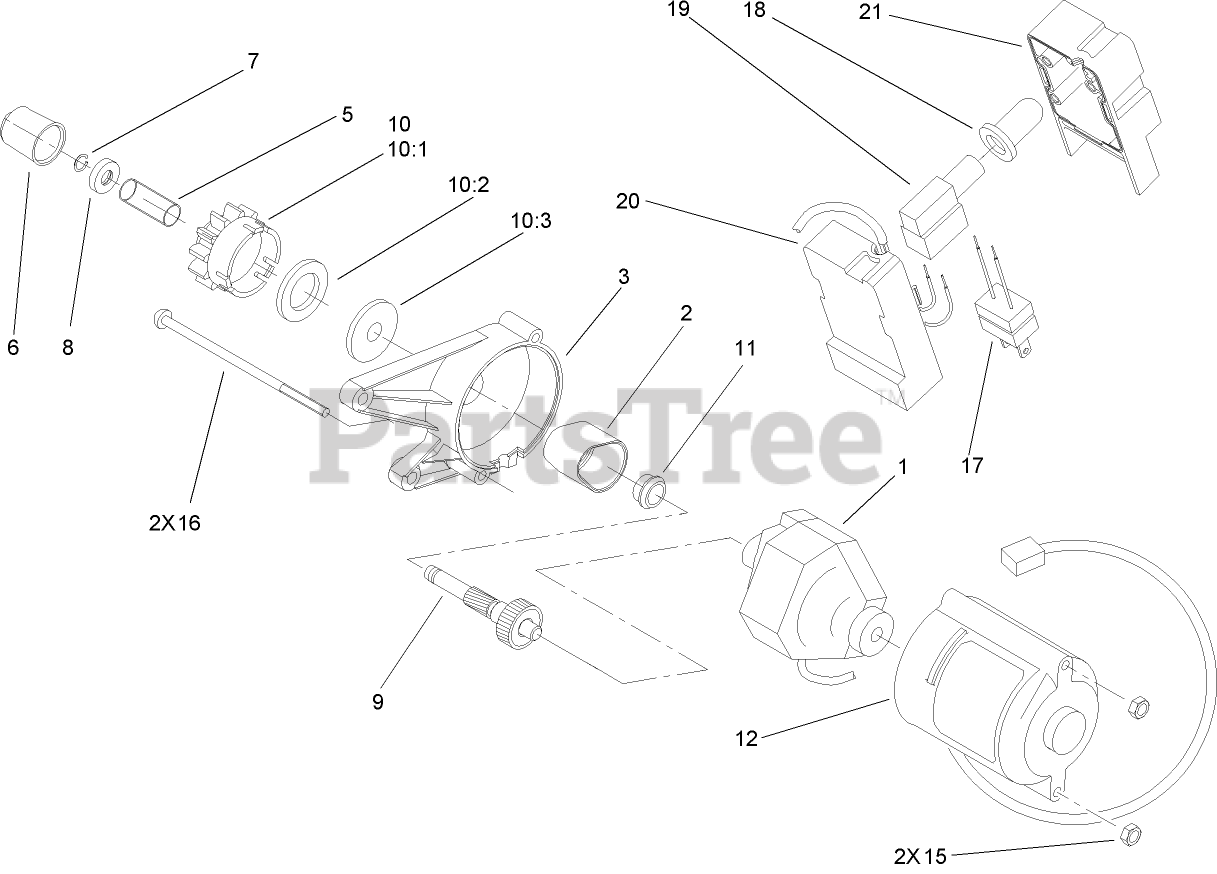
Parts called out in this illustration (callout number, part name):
2	COVER-GEAR
3	HOUSING-UPPER, STARTER
5	SPRING
6	CAP-PINION
7	RING-LOCK
8	STOP-PINION
9	SHAFT AND GEAR ASM
10	PINION ASM
10:2	PINION
10:3	RING-RUBBER
11	BUSHING
12	HOUSING-LOWER, STARTER
15	NUT-LOCK, NI
17	PLUG-POWER
18	BOOT-SWITCH
19	SWITCH-STARTER
20	SWITCH-BASE, HOUSING
21	HOUSING-CAP, SWITCH
